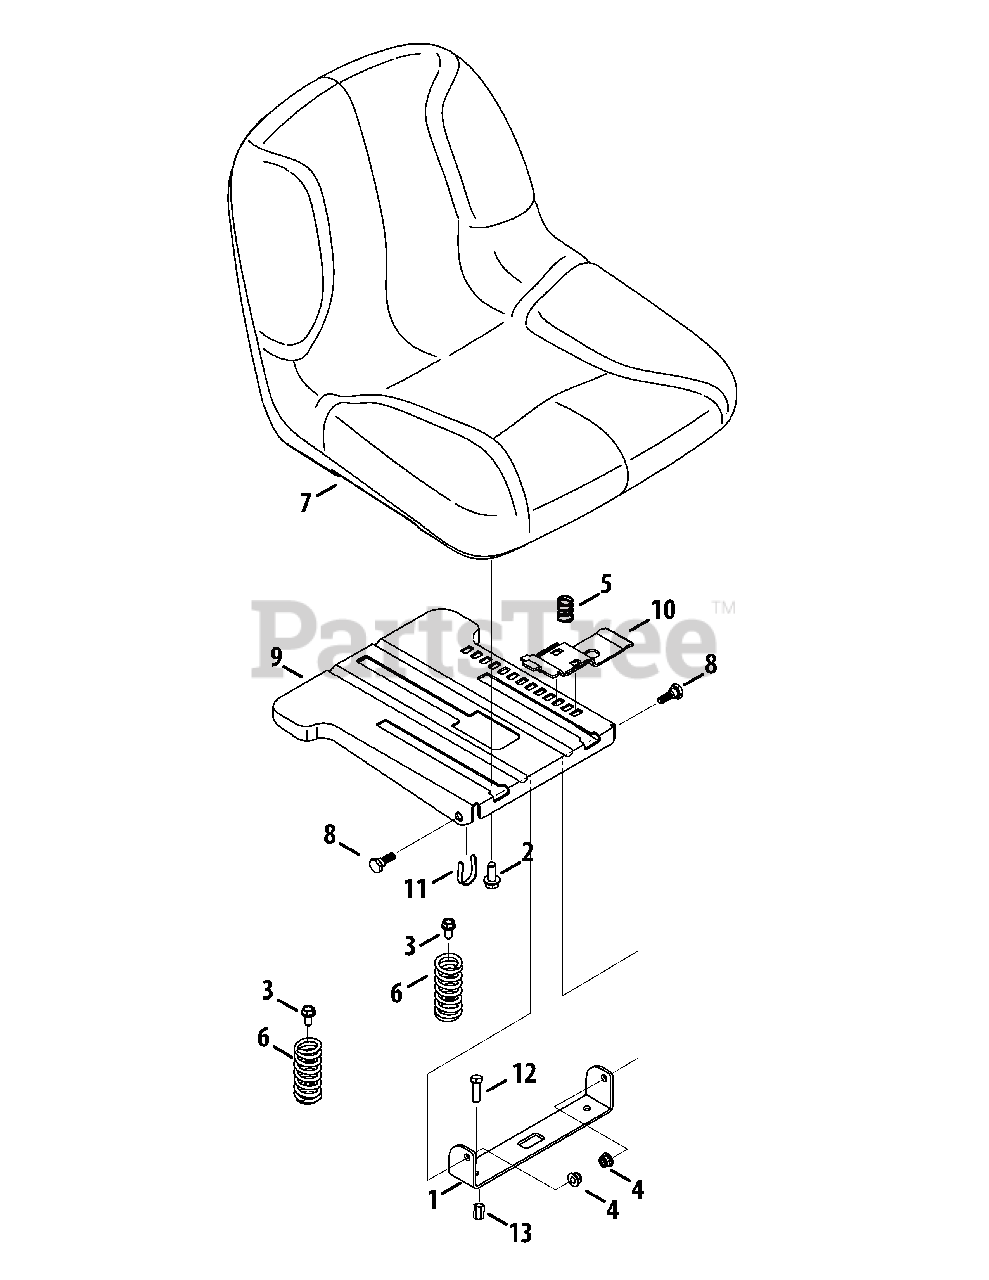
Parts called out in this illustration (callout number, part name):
1	Seat Bracket
2	Hex Flange Bolt 3/8-16 x .875
3	Hex Washer Screw 5/16-18 x .750
4	Flange Lock Nut 5/16-18
5	Compression Spring .68 x 1.065 x .055
6	Compression Spring 1.50 x 3.90 x .200
7	Seat
8	Shoulder Screw 5/16-18 x .437 x .268
9	Seat Mount Bracket
10	Seat Adjustment Lever
12	Hex Hd. Cap Screw 5/16-18 x 1.0 Gr. 5
13	Rivet Nut 5/16-18
